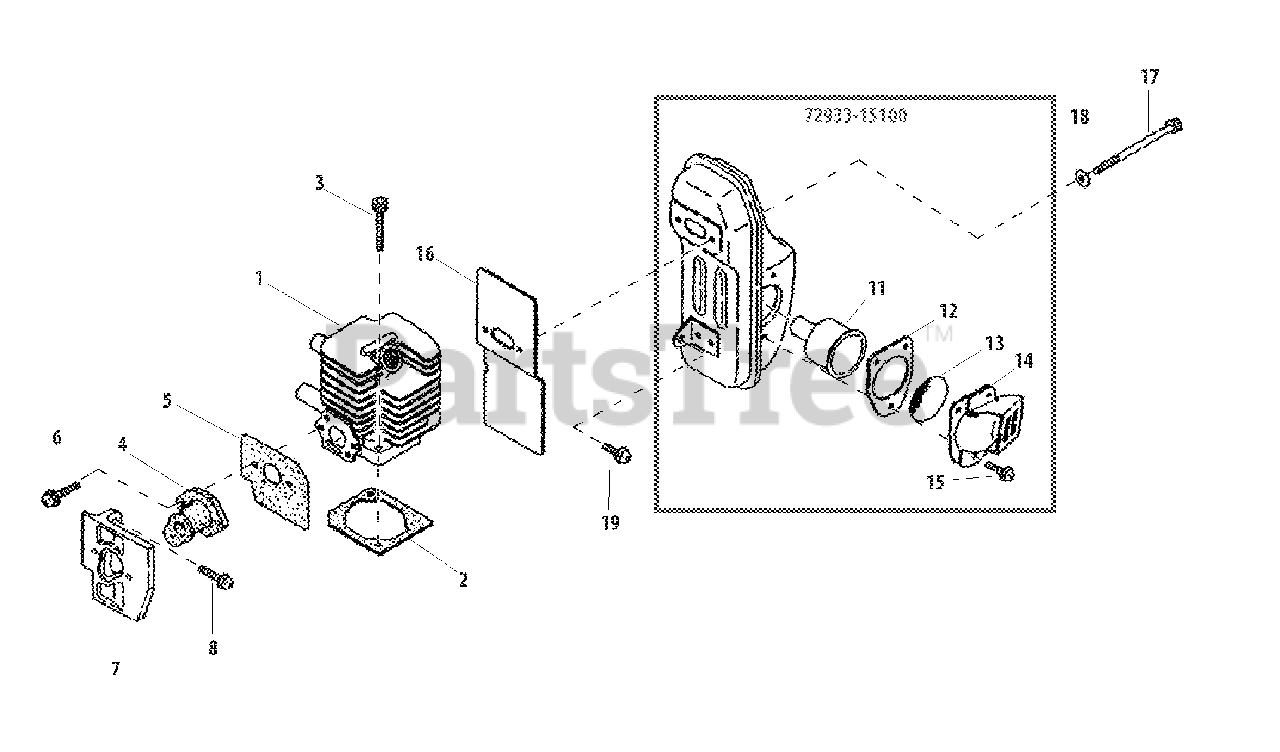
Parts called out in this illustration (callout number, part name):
1	CYLINDER
2	GASKET, CYLINDER
3	SCREW - 5X20
4	BOOT
5	GASKET
6	SCREW - 5X16
7	BRACKET
8	SCREW - 5X16
11	CHAMBER
12	GASKET
13	SCREEN, SPARK ARRESTOR
14	GUIDE, EXHAUST
15	SCREW - 4X10
16	GASKET
17	SCREW - 5X55
18	WASHER - 5
19	SCREW - 5X16
72933-15100	MUFFLER ASSY
